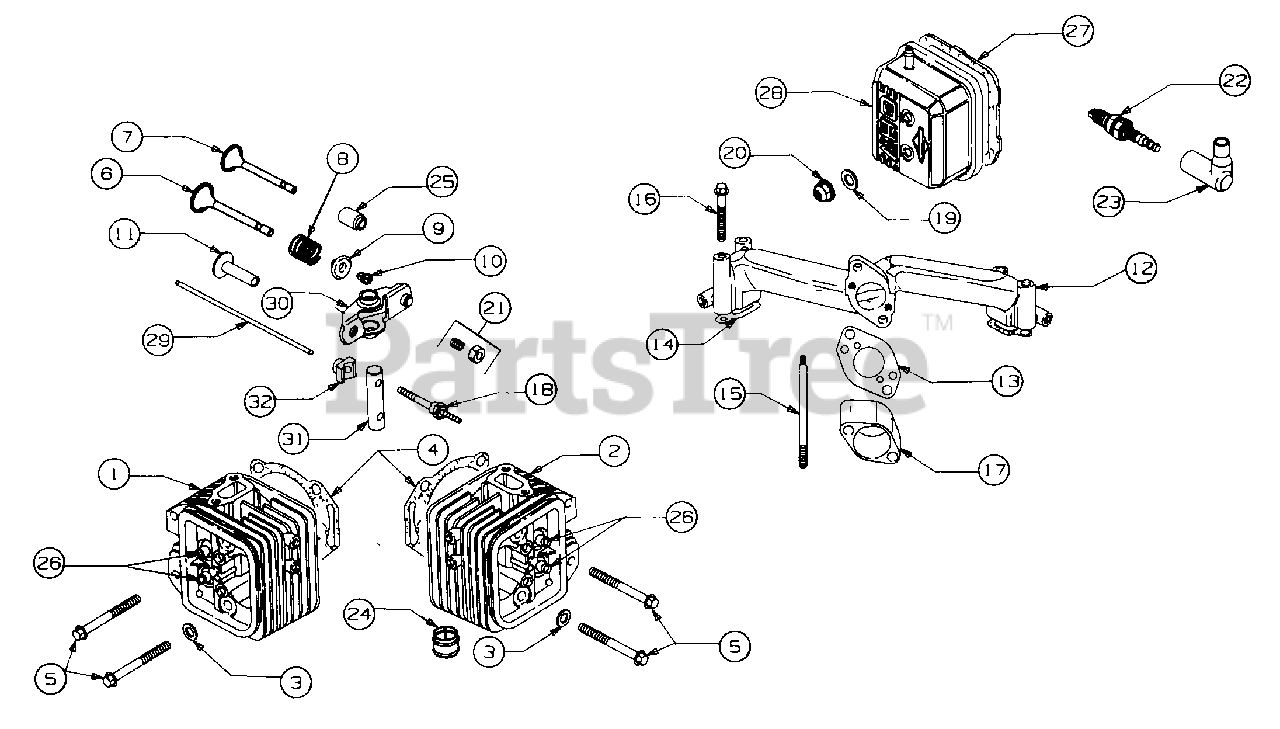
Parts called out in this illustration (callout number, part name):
1	Head, Cylinder #1
2	Head, Cylinder #2
3	Washer, Cylinder Head
4	Gasket, Cylinder Head
5	Screw, Cylinder Head
6	Valve, Exhaust
7	Valve, Intake
8	Spring, Valve
9	Retainer, Valve Spring
10	Retainer, Valve
11	Tappet, Valve
12	Manifold, Intake
13	Gasket, Carburetor Mtg
14	Gasket, Intake Manifold
15	Stud, Carburetor Mtd
16	Screw, Sem
17	Spacer, Carburetor
18	Stud, Rocker Arm
19	Washer, Valve Cover
20	Nut, Nylock
21	Screw, Valve Adjusting
22	Plug, Spark
23	Elbow, Spark Plug
24	Liner, Exhaust Port
25	Seal, Valve Guide
26	Guide, Valve
27	Gasket, Valve Cover
28	Cover, Valve
29	Rod, Push (Steel)
30	Arm, Rocker
31	Shaft, Rocker Arm
32	Support, Rocker Arm
